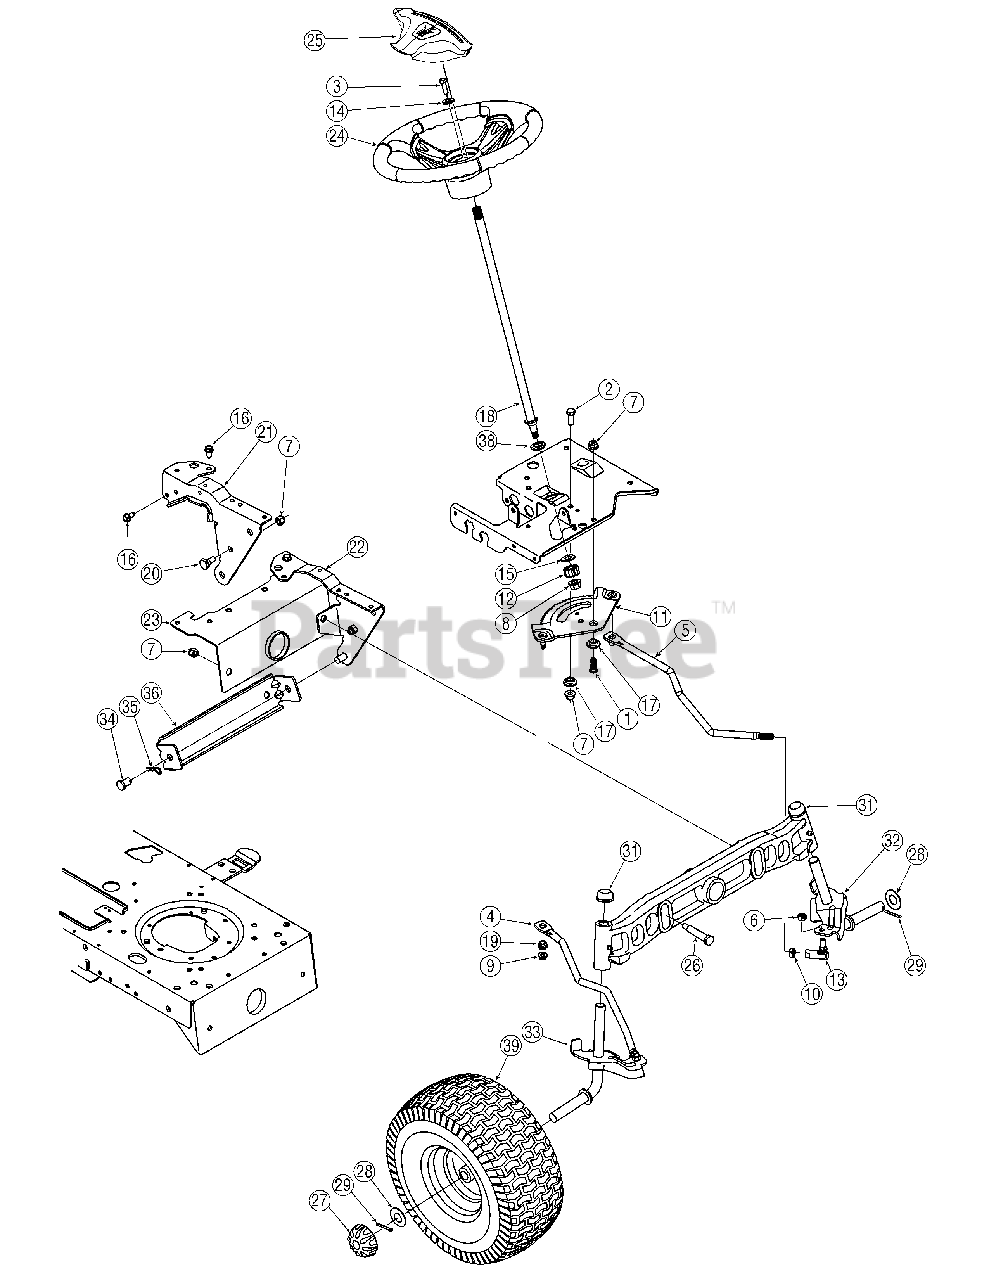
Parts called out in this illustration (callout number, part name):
1	Hex Screw, 3/8-16, 1.00, Gr5
2	Hex Screw, 3/8-16, 1.00, Gr5
3	Hex Screw, 5/16-18, 1.00, Gr5
4	Link, Drag, RH
5	Link, Drag, LH
6	Nut, Hex Lock, 3/8-24
7	Nut, Flange Lock, 3/8-16, Grf, Nylon
8	Nut, Flange Lock, 7/16-20
9	Nut, Flange Lock, 5/16-18, Gr5
10	Nut, Jam, 7/16-20, Gr2
11	Gear, Steering, 11/90 Ratio
12	Gear, Pinion, Steering
13	Ball Joint, 7/16-20, Lock
14	Washer, Flat,.406 x.875 x.105
15	Washer, Flat,.51 x 1.12 x.06
16	Screw, 5/16-12, 0.750
17	Spacer, Shoulder,.38 x 1.00 x.31
18	Shaft, Steering,.625 OD x 24.25 LG
19	Plastic Bushing.380 ID
20	Screw, Shoulder,.498 x.340, 3/8-16
24	Steering Wheel, 3 Spoke, Soft Grip
25	Steering Wheel Cover
26	Shlder Screw,.5 x 2.2, 3/8-16
27	Deluxe Hub Cap
28	Flat Washer,.78 x 1.589 x.06
29	Cotter Pin, 5/32 x 1.25
31	Cast Iron Pivot Bar
32	LH Axle Assembly,.750
33	RH Axle Assembly,.750
34	Pin, Clevis,.50 x.78
35	Cotter Pin, Inter,.080 x 1.5625
38	Hex Flange Bearing
